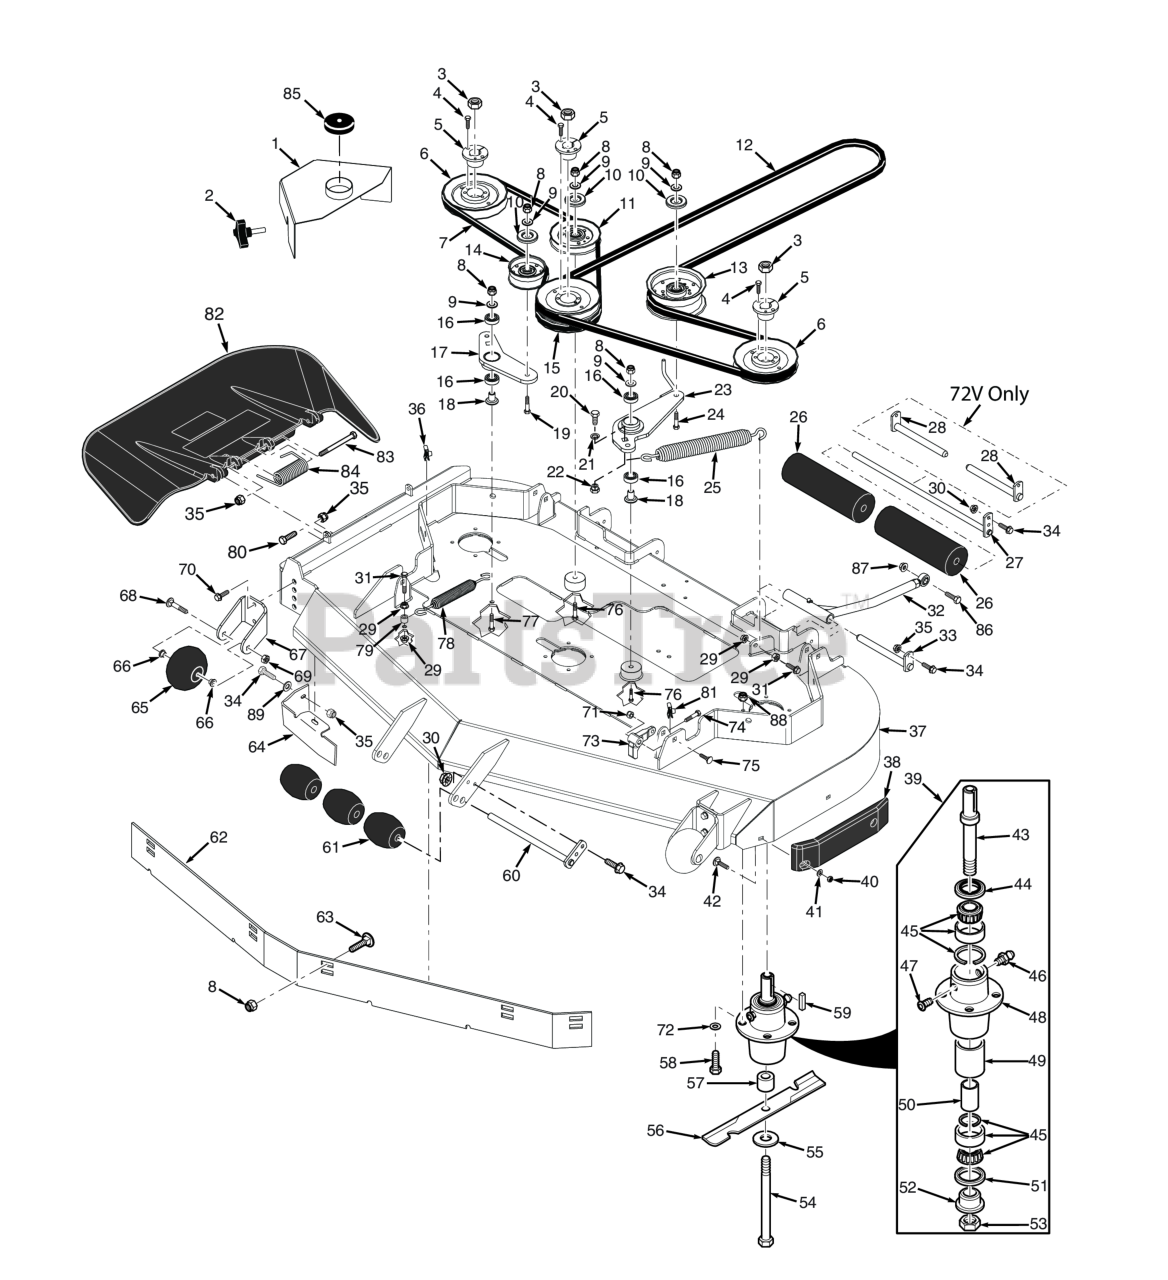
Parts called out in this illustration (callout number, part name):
1	Belt Cover, LH (INCL 85)
2	Knob, w/stud 3/8-16 x 1-1/4"
3	Hex Locknut, Elastic Stop, 3/8-16
4	Bolt, Hex Head 1/4-20 x 1" Grade 8 Black
5	Hub, Tapered 1-1/8" Bore
6	Pulley, Tapered Bore 6.33" Dia.
7	Belt, Deck Drive R.H.
8	HEX NUT, ELASTIC STOP LOCK, 3/8-16
9	Flatwasher, 3/8 (.391 x .938 x .105 HD) Grade 8
10	Quick Pin, 5/16" Dia.
11	IDLER PULLEY, "V" GROOVE
12	Belt, Cutter Deck Drive - Cat
13	Pulley, Idler 5" Dia.
14	Pulley, 3-1/2" Dia.
15	Pulley, Double Groove 6.33" Dia.
16	BEARINGS, BALL, NEUTRAL RETURN
17	ldler Arm Assembly, R.H. Drive
18	Pivot, Idler Short
19	Capscrew, Hex Head 3/8-16 x 2-1/2"
20	Bolt, Hex Head 7/16-14 x 1"
21	Lockwasher, 7/16� Spring
22	Boss, Spring Anchor - LH
23	Idler Arm
24	Bolt, Hex Head 3/8-16 x 3" - 52"
25	Spring, L.H. Deck Drive
26	Wheel, Anti-ScalpRelief Fitting, Tapered Spindle
27	Roller Shaft (small frame)
29	NUT, 3/8-16 SERRATED FLANGE HEX HEAD
30	Nut, Flange Head Elastic Stop 5/16-18
31	Bolt, Hex Head 3/8-16 x 1-1/2" Grade 8 Black
32	Pusharm Assembly, LH
33	Shaft Weldment, Pusharm
34	Bolt, Heax Head 5/16-18 x 1" (48V / 52V)
35	HEX NUT, ELASTIC STOP LOCK, 5/16-18
36	U-Nut, 3/8-16
37	Cutter Deck w/Decals
38	Pad, Deck Wear
39	Cutter Spindle Assembly
40	Nut, Center Lock, 5/16-18(32)
41	Flatwasher, 5/16-.344 x .688 x .065 (48V / 52V)
42	Bolt, 5/16-18 x .75 RHSN Carriage
43	Spindle Shaft, Tapered Brng
44	SEAL, 2.00 O.D. X 1.50 BORE
45	Tapered Bearing Set (Two Bearings W/Race)
46	GREASE FITTING, STR. 1/4-28 SELF TAP.
47	RELIEF FITTING, TAPERED BEARING SPINDLE
48	Housing, Spindle
49	Spacer, Outside, Cutter Spindle
50	SLEEVE, CUTTER SPINDLE
51	Seal, 2.00" O.D. x 1.625" Bore
52	SPINDLE BUSHING, BOTTOM
53	Nut , Spec ial 1 -1/ 1 6 - 1 8
54	BOLT, HEX HEAD, 5/8-11 X 9-1/2 GR.5
55	Flatwasher, 5/8-.688 x 1-3/4 x .134 HD
56	Cutter Blade, 21" (35BV & 37BV-EFI)
57	Spacer, Spindle Bottom
58	Bolt, Hex Head 5/16-18 x 1-3/4" Grade 8
59	Key, 1/4 x 1/4 x 2.0"
60	Shaft Weldment, Guide Roller
61	Wheel, Anti-Scalp
62	Baffle Custom-Cut, 61V (7-Position)
63	Carriage Bolt, 3/8-16 x 1.0"
64	Turbo Baffle, Bolt On
65	Bolt, Carriage 3/8-16 x 4"
66	Bushing, .376" I.D. Oilite
67	Bracket, Anti-Scalp Wheel
68	Bolt, Hex Head 3/8-16 x 3-1/2"
69	Bolt, Hex Head 3/8-16 x 1" Ser. Flg.
70	Capscrew, 3/8-16 x 1.0" Serrated Flange Hex Hd
71	HEX LOCKNUT, ELASTIC STOP, 7/16-14
72	Lockwasher, 5/16 (.317 x .586 x .078) Helical Spring
73	Lever, Deck Level
74	Bolt, Hex Head 3/8-16 x 2-1/2" Soecial Lock
75	Bolt, Carriage 7/16-14 x 2-1/4"
76	Bolt, Hex Head 3/8-16 x 3" - 52"
77	Bolt, Hex Head 3/8-16 x 2-1/4" - 61"
78	Spring, RH Deck Drive
79	SPACER, IDLER
80	Bolt, Hex Head 5/16-18 x 1-1/2" - Front
81	U-Nut, 3/8-16 (short)
82	Discharge Chute Advantage - Large
83	Bolt, 5/16-18 x 4-3/4" Hex Head
84	Spring, Discharge Chute
87	Nut, Center Lock 5/8-11
88	Lock Nut, 5/16-18 Elastic Stop Grade 8
89	Flatwasher, 5/16-.375 x .875 x .083 (35BV & 37BV-EFI)
